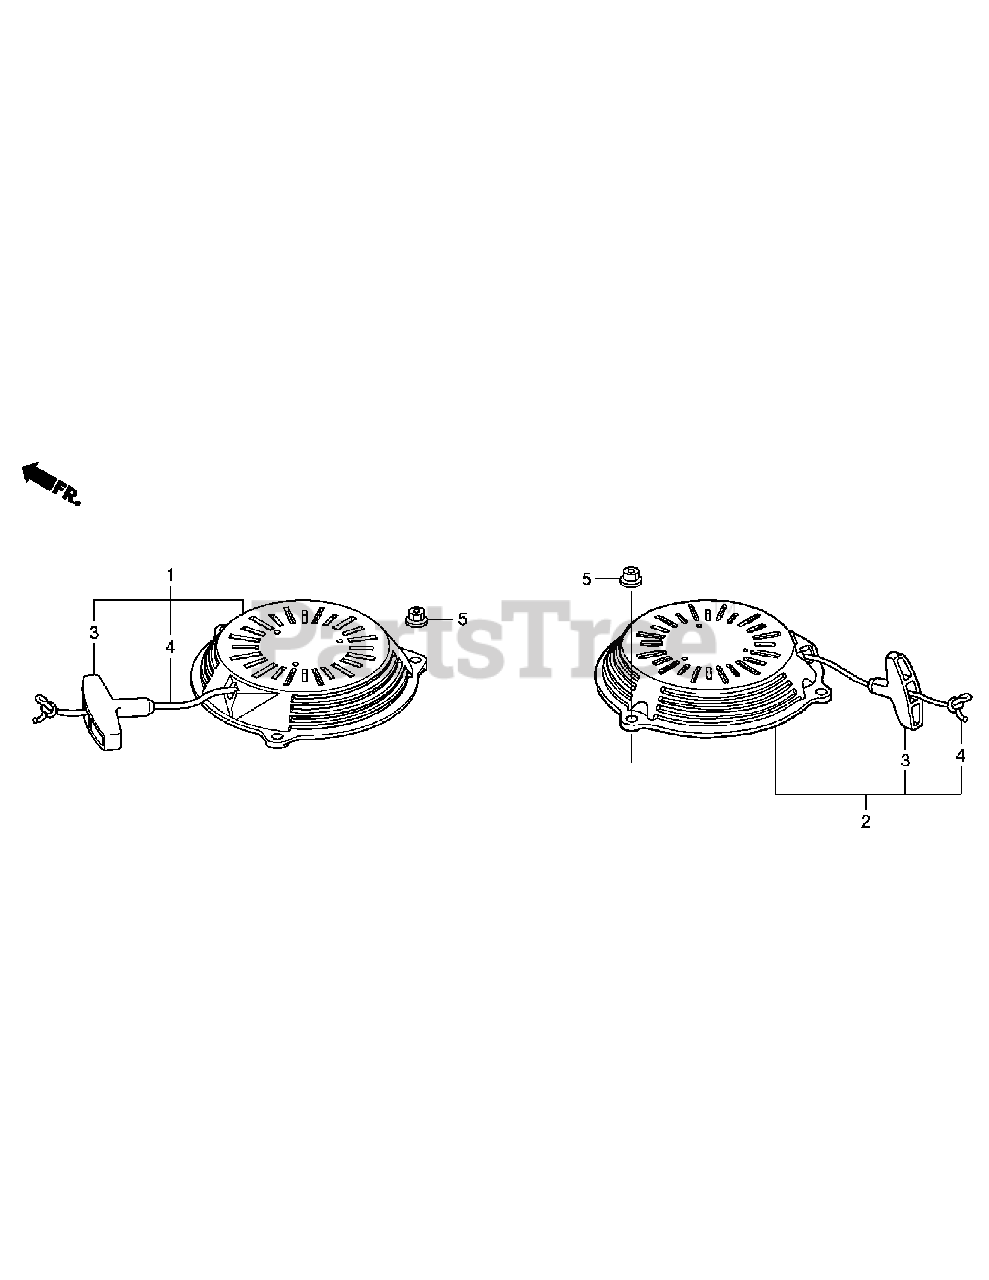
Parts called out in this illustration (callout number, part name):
1	PRI; STARTER ASSY., RECOIL *NH1*
3	GRIP, STARTER
4	ROPE, RECOIL STARTER
5	NUT, FLANGE (6MM)
